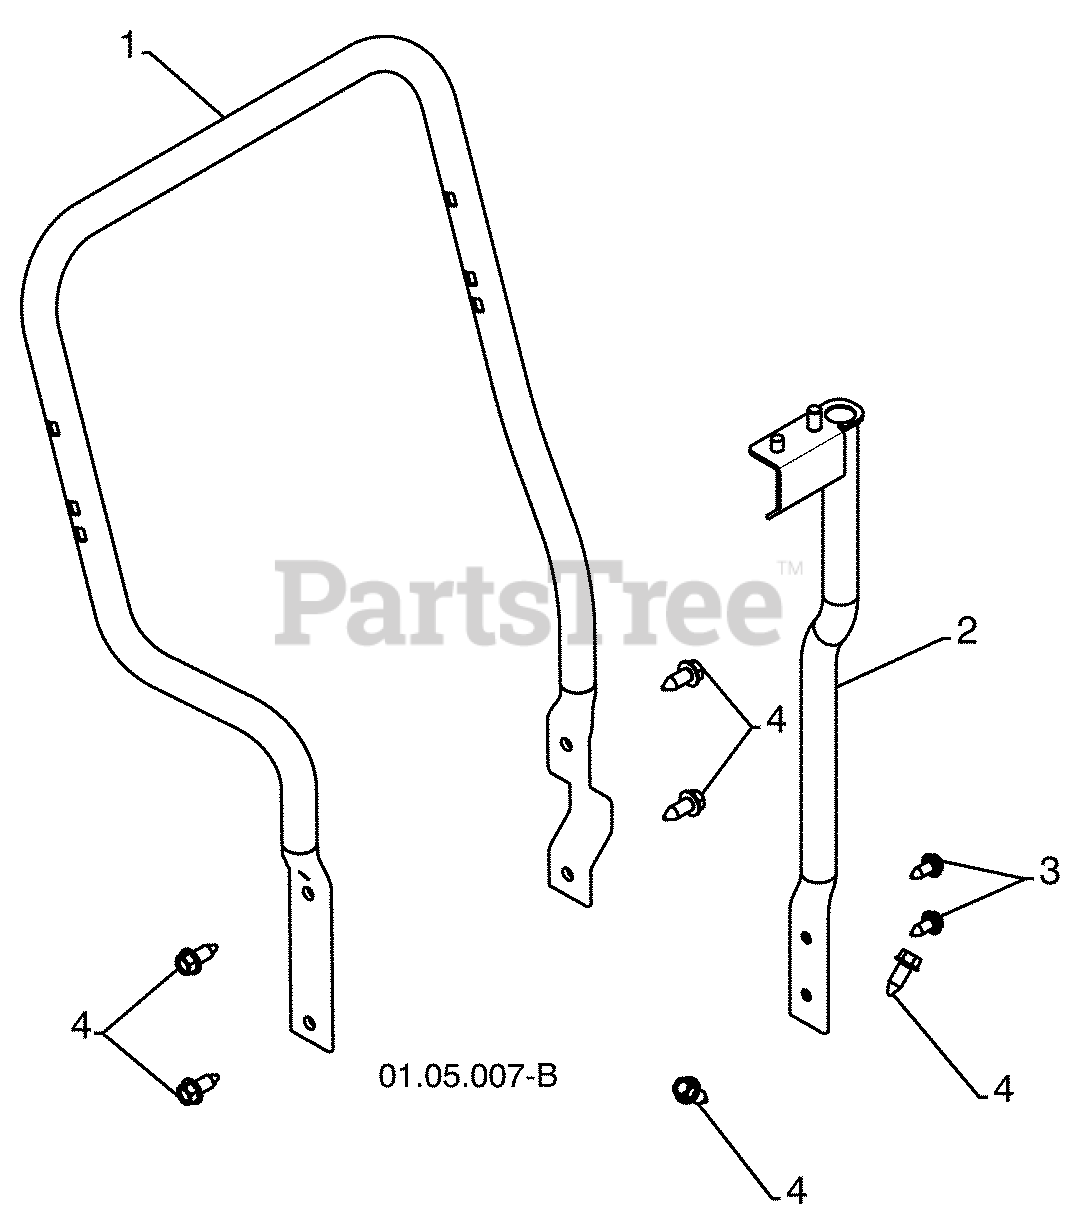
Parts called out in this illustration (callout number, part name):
1	LOWER TUBE GRAY
2	PIVOT SUPPORT
3	BOLT 5/16-18 X .750
4	SCREW 3/8-16 X 1.00
